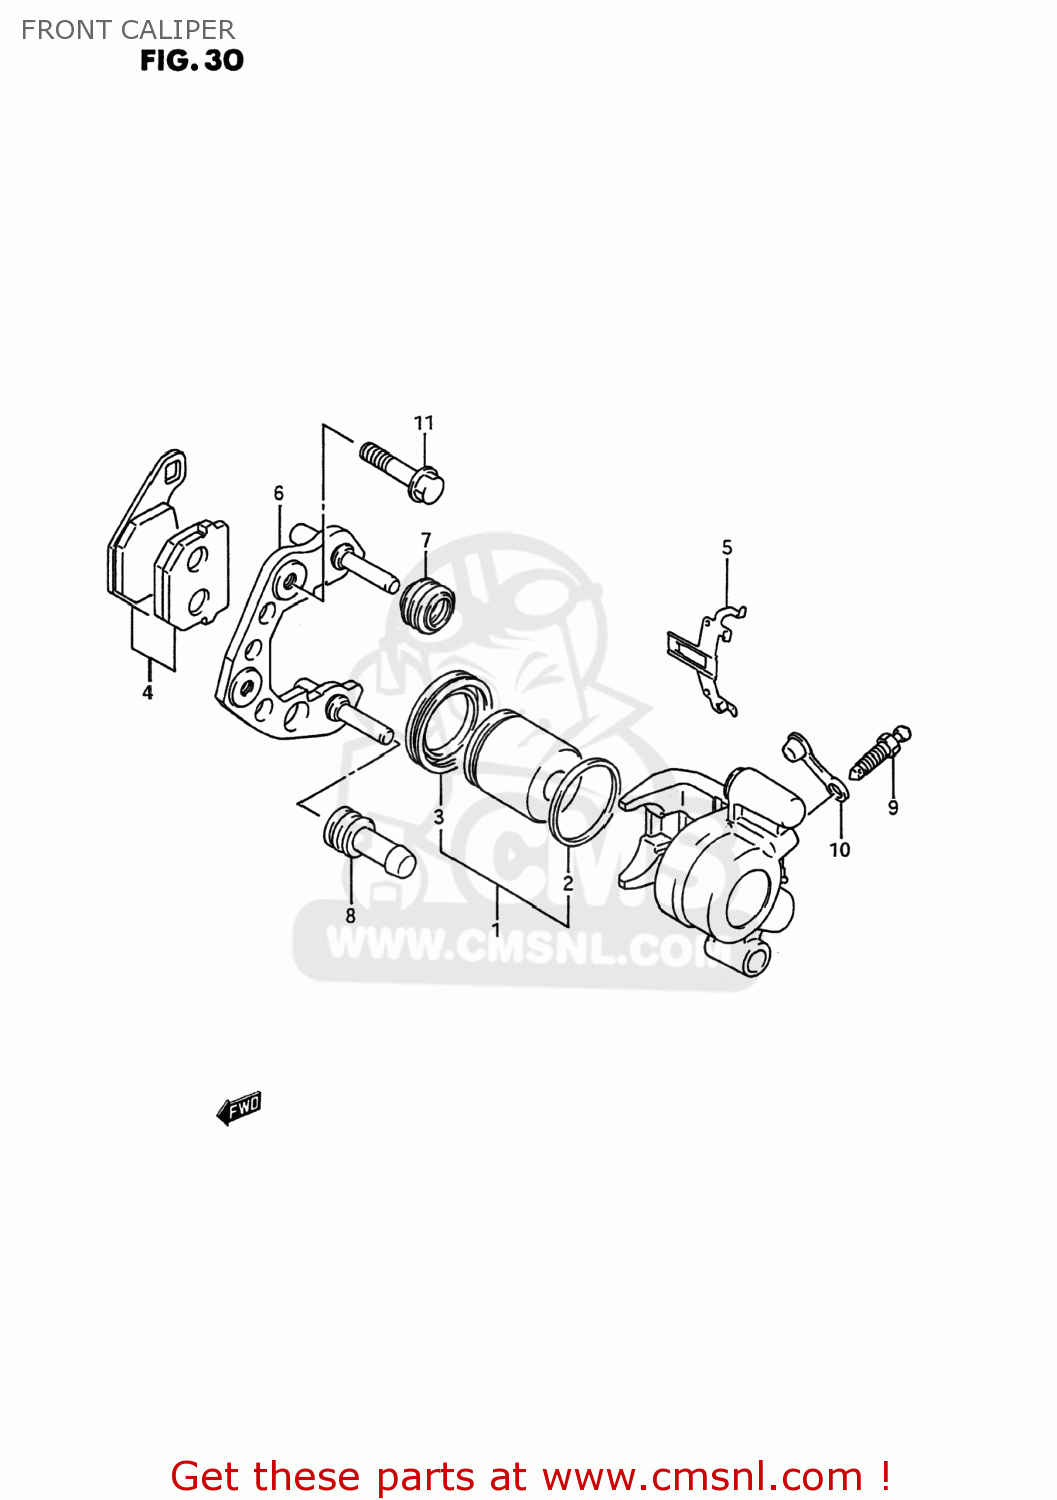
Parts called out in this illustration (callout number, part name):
1	PISTON SET
2	SEAL
3	BOOT
4	PAD SET (NAS)
5	SPRING,PAD
6	CARRIER
7	BOOT,AXLE
8	INSULATOR,AXLE
9	BLEEDER
10	CAP,BLEEDER
11	BOLT(8X35)
